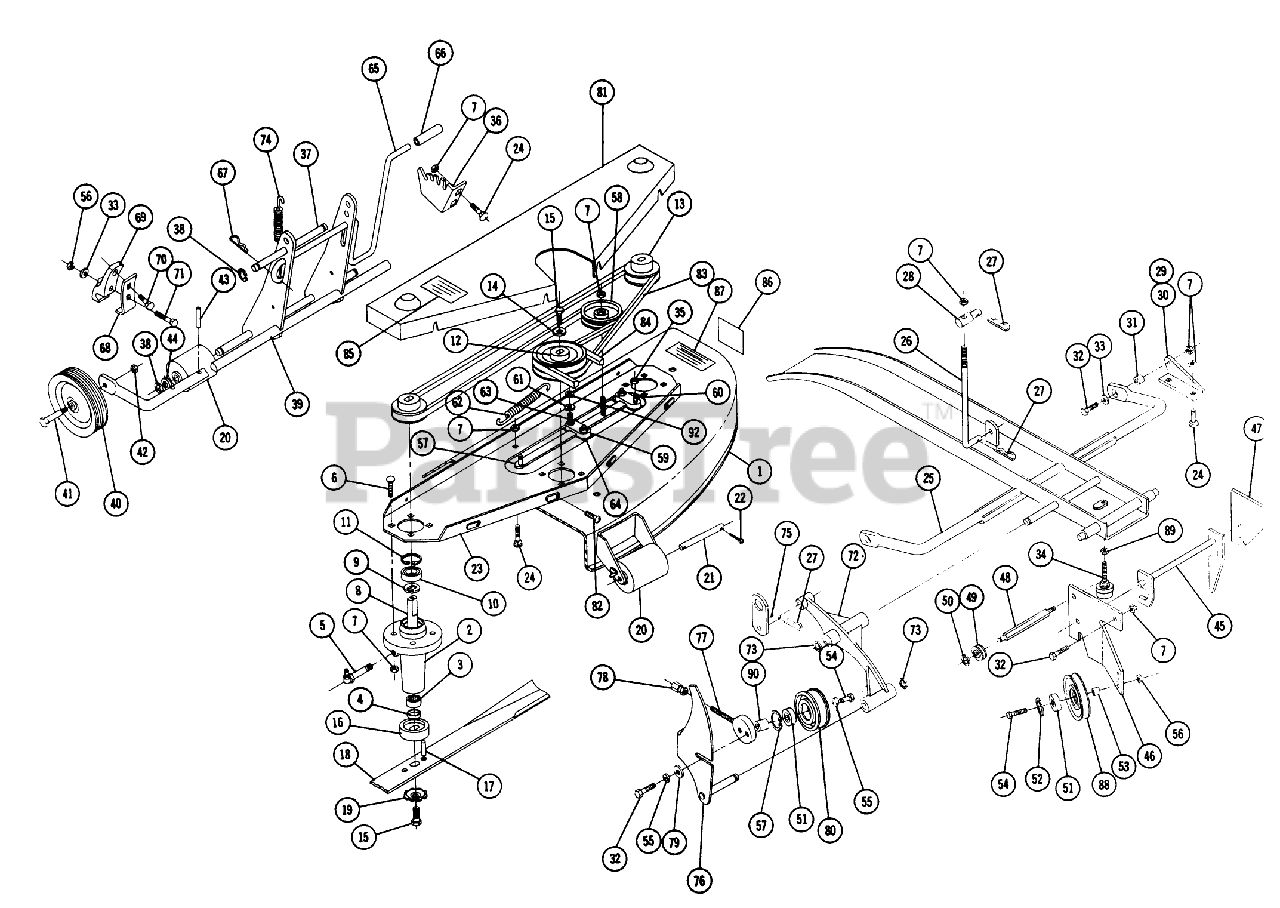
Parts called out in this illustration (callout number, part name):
6	Bolt 3/8-16 x 1
7	3/8-16 E.S.
9	WASHER
11	INT SNAP RING
14	WASHER
15	Bolt 3/8-16 x 7/8
17	SPIROL ROLL PIN
22	Cotter Pin
24	Bolt-3/8-16 x 3/4
27	Hairpin
28	TRUNNION-LIFT
29	Bracket-Deck R.H.
30	Bracket-Deck L.H.
32	Bolt 3/8-16 x 1
33	Washer
35	Nut 5/16-18
39	Ass-y Gage Wheel Support
41	BOLT-SHOULDER
42	3/8-16 Jam Nut
43	Roll Pin
44	Washer
46	MOUNTING BRACKET *R
50	Lock Rod
51	BEARING
52	INTERNAL SNAPRING
53	SPACER
54	Bolt, 3/8-16 x 1/2
55	Lockwasher
60	Bolt-5/16-18 x 1/4
61	Washer
62	SPRING *R
63	Bolt-5/16-18 x 1 1/2
66	Grip Handle
67	Hairpin
69	SUPPORT AXLE
70	Bolt-Carriage
71	Bolt Carriage 3/8-16 x 1
74	Spring
79	WASHER
83	V-BELT
85	Decal Belt Installation
89	Nut-Nylok
91	Hairpin
92	Nut-Nylok
